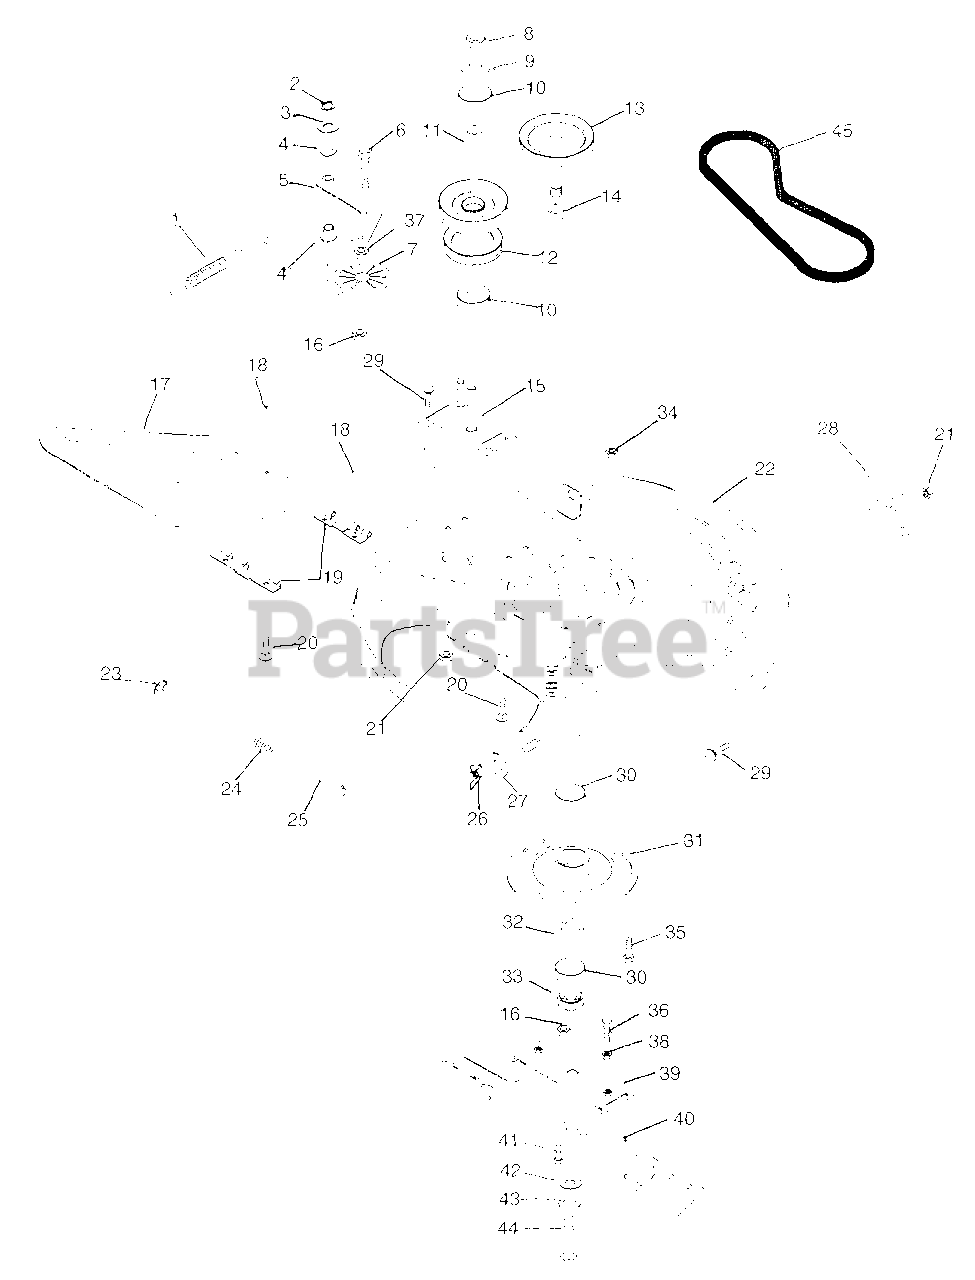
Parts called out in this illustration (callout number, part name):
1	SG-TENS .113X.812X7.00
2	RG-RTNG-INT .697X.93
3	WSHR-FL-STL .505X.880X.072 PL
4	BSHG-FLG .500X.625X.187X.750FD
5	IDLER ARM
6	BLT-HEX .38-16X1.75 PL GR2
7	IDLER-FLAT 2.75 X .38 DAYCO
8	NUT-LK-NYL.625-18 PL
9	WSHR-FL-STL .640X1.005X.062 PL
10	BRG-BALL .625X1.375X.44
11	SPACER .647X.812X1.780
12	JACKSHAFT
13	MOWER SHEAVE 32"
14	SPACER
15	MOUNT PLATE 32"
16	NUT-LK TOP .375-16 GR C YWZC
17	32" DEFLECTOR W/DECAL
18	NUT-LK-CTR .250-20 PL
19	HINGE PLATE
20	BLT-RDHDSQNK .25-20X.50 SHT PL
21	NUT-FLG. .312-18 PL
22	32IN PAN WELDMENT
23	RG-RTNG-EXT .312X.025
24	SG-TORS .090X.37X.63
26	NUT-WING W/INSERT .312 - 18
27	WSHR-FL-STL .328X.875X.062 PL
28	MOWER ADJUSTMENT TAB
29	BLT-RDHDSQNK.31-18X.75GR5SHTPL
30	BRG-BALL .750X1.781X.61
31	SPINDLE HOUSING
32	SPACER .753X1.000X1.140
34	NUT-LK-CTR .375-16 GR A PL
35	BLT-HEX .38-16X.75 PL GR5
36	BLT-HEX .38-24X1.25 PL GR5
37	NUT-JAM .375-16 PL
38	NUT JAM .375-24 PL
39	BLADE TRAY WELDMT
40	32" BLADE
41	BLT-HEX .38-16X1.00 PL GR5
42	WSHR-FL-STL .505X1.140X.250
43	WSHR-LK .438X.133 HVY
44	BLT-HEX .44-20X1.75 PL GR5
45	V-BELT, 4L-WRAPPED
